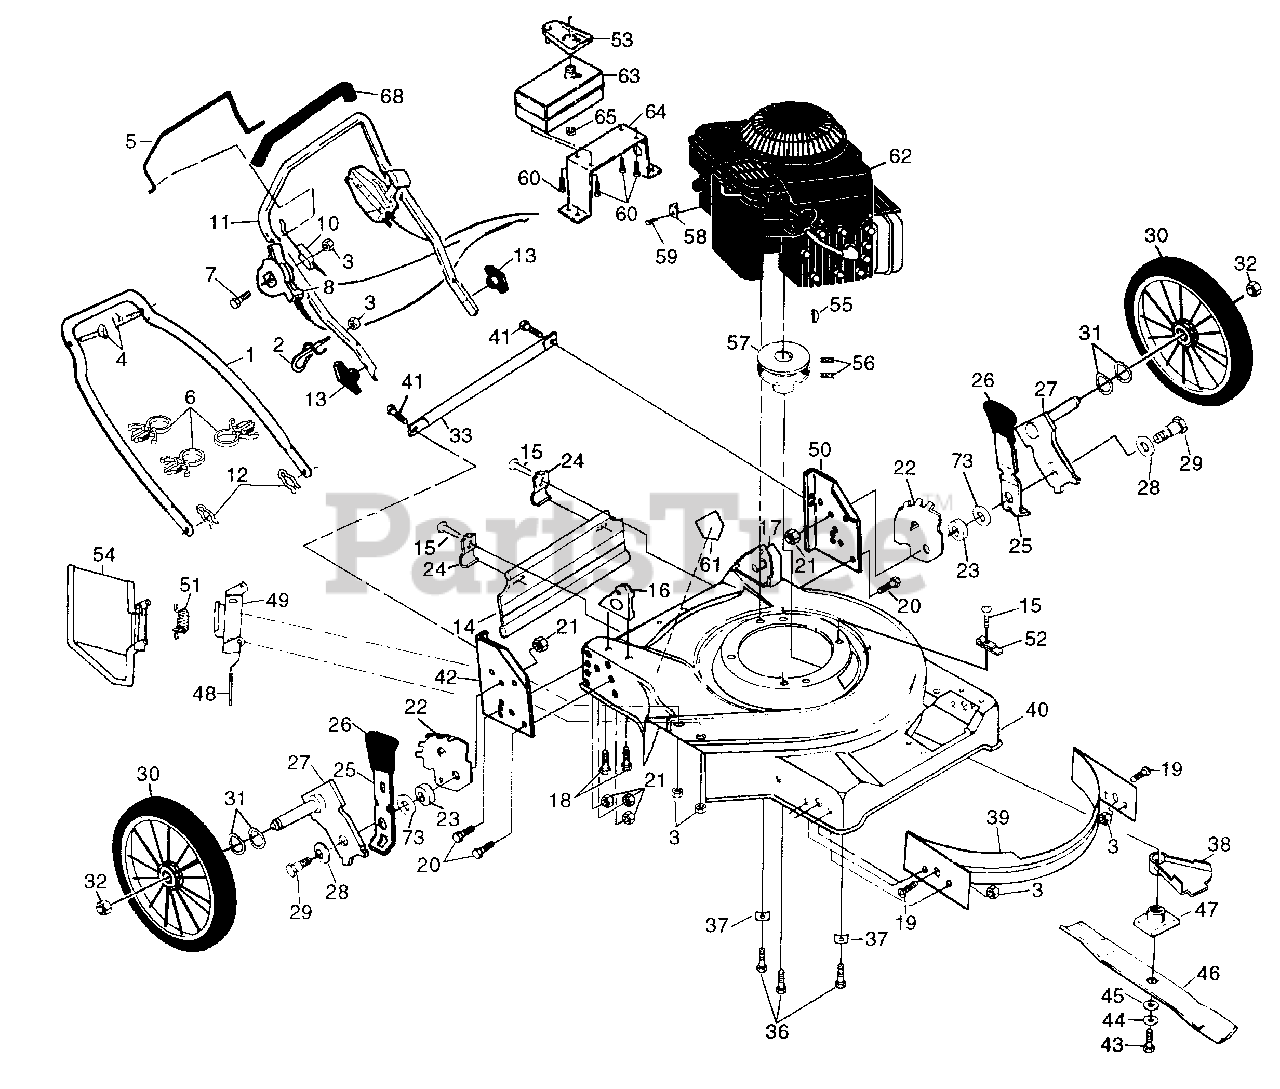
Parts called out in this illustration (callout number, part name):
1	Lower Handle (AYP part number)
2	Rope Guide
3	Locknut 1/4-20 (AYP part number)
4	Handle Bolt (AYP part number)
5	Control Bar (AYP part number)
6	Cable Clip (AYP part number)
7	Hex Washer Head Screw 1/4-20 x 2-1/8 (AYP part number)
8	Throttle Control
10	Engine Zone Cable
11	Upper Handle (AYP part number)
12	Hairpin Cotter (AYP part number)
13	Handle Knob (AYP part number)
14	Rear Skirt (AYP part number)
15	Hex Head Screw #10 (AYP part number)
16	Handle Bracket Assembly (Right) (AYP part number)
17	Handle Bracket Assembly (Left) (AYP part number)
18	Screw 5/16-18 x 3/4 (AYP part number)
19	Flat Machine Screw 1/4-20 x 3/4 (AYP part number)
20	Hex Head Bolt 3/8-16 x 3/4 (AYP part number)
21	Locknut (AYP part number)
22	Wheel Adjusting Bracket (R.R.) (AYP part number)
23	Spacer (AYP part number)
24	Skirt Bracket (AYP part number)
25	Selector Spring (AYP part number)
26	Selector Knob
27	Axle Arm Assembly (AYP part number)
28	Rear Spring Washer (AYP part number)
29	Shoulder Bolt 3/8-16 (AYP part number)
30	Wheel & Tire Assembly (Rear) (AYP part number)
31	Wave Washer (AYP part number)
32	Nut (AYP part number)
33	Rod Support (AYP part number)
35	Fuel Tank Cap (AYP part number)
36	Thread Rolling Screw 3/8-16 x 1 (AYP part number)
37	Engine Washer (AYP part number)
38	Debris Shield
39	Front Baffle
40	Mower Housing Kit
41	Screw (AYP part number)
42	Wheel Support Bracket R.H. (AYP part number)
43	Hex Head Screw 3/8-24 x 1-3/8 Gr. 8
44	Helical Washer 3/8 (AYP part number)
45	Hardened Washer (AYP part number)
46	22" Blade (AYP part number)
47	Blade Adapter
48	Hinge Rod (AYP part number)
49	Housing Bracket (AYP part number)
50	Wheel Support Bracket L.H. (AYP part number)
51	Torsion Spring (AYP part number)
52	Guide Clip (AYP part number)
53	Deflector (AYP part number)
54	Discharge Guard (AYP part number)
55	Hi-Pro Key (AYP part number)
56	Set Screw (AYP part number)
57	Engine Pulley (AYP part number)
58	Cable Clamp (AYP part number)
59	Screw #10 x 5/8 (AYP part number)
61	Danger Decal (AYP part number)
63	Fuel Tank (AYP part number)
64	Fuel Tank Bracket (AYP part number)
65	Fuel Line Clamp (AYP part number)
68	Handle Grip (AYP part number)
73	Flat Washer 3/8 (AYP part number)
